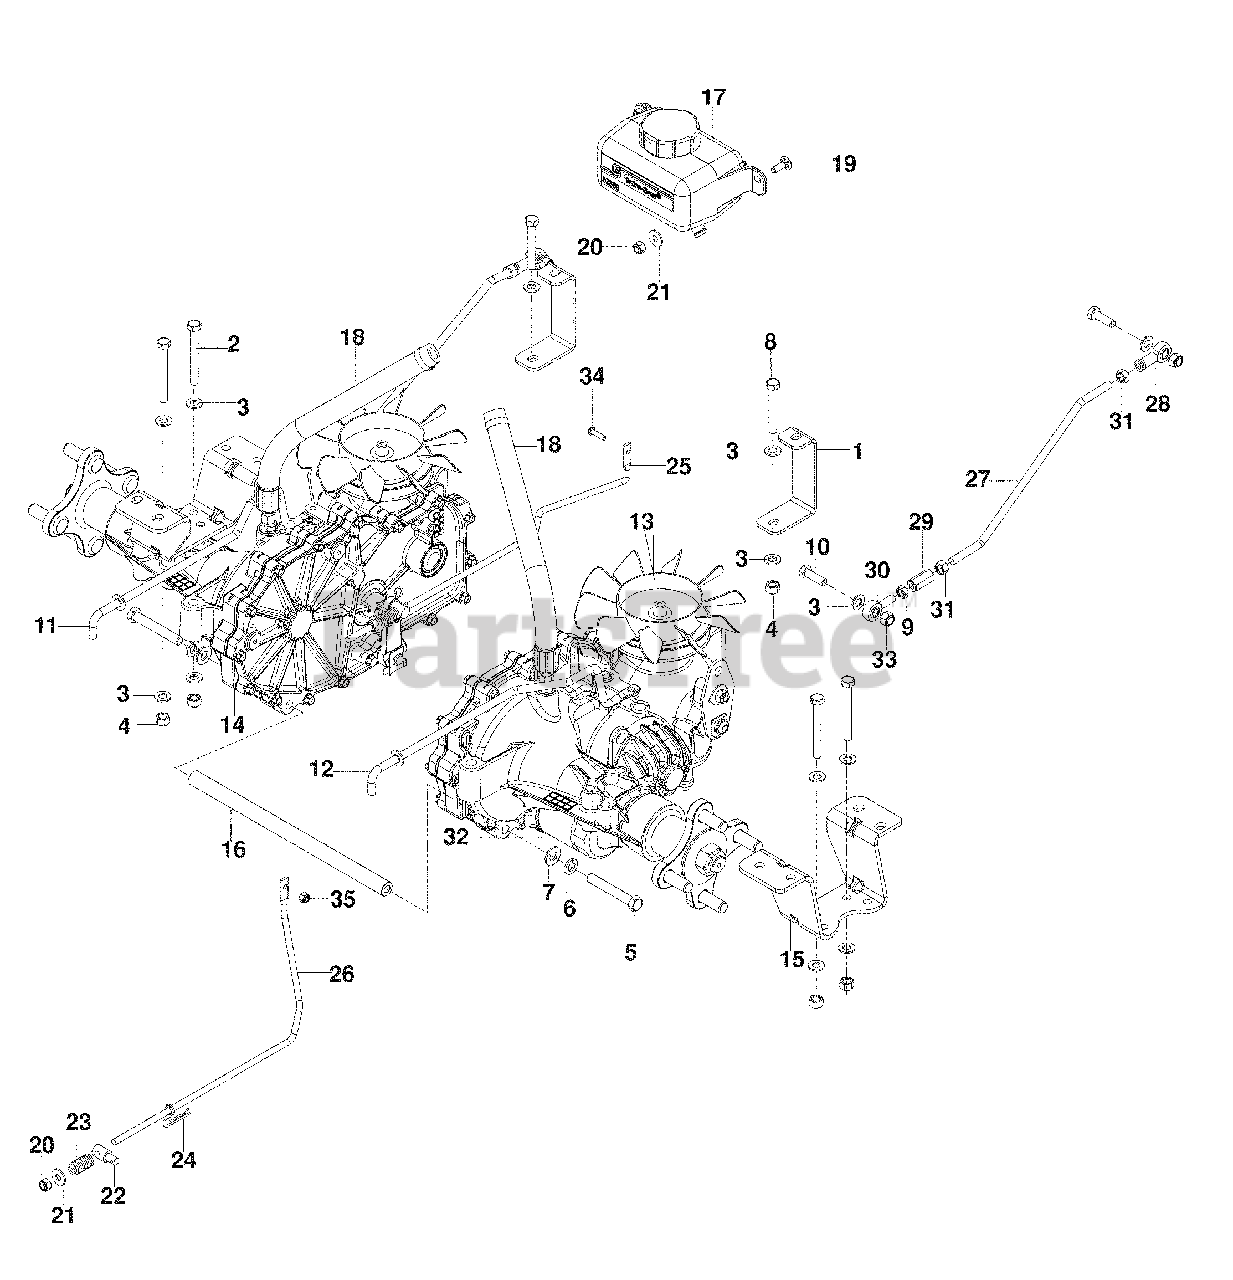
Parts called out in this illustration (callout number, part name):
1	SUPPORT, TRANSMISSION
2	HCS 5/16-18 x 2¾
3	WASHER 5/16 SAE FLAT
4	NUT 5/16-18 HEX NYLOC
5	HCS 3/8-16 x 2½
6	WASHER 3/8 SPLT LOCK
7	WASHER 3/8 SAE FLAT
8	HCS 5/16-18 x 2¼
9	NUT 5/16-24 HEX JAM LH
10	HCS 5/16-18 x 1
11	LINK ARM, BYPASS, RT
12	LINK ARM, BYPASS, LT
13	TRANS, ZT-2800 RT
14	TRANS, ZT-2800 LT
15	EZT MOUNT, REAR
16	SPACER TUBE, EZT
17	EXPANSION TANK w/CAP
19	RHSNB ¼-20 x ¾ GR2
20	NUT ¼-20 HEX NYLOC
21	WASHER ¼ FLAT
22	BRAKE SWIVEL
24	HAIRPIN COTTER
25	LINKAGE, BRAKE LT
26	LINKAGE, BRAKE RT
27	ROD, MOTION CONTROL
28	ROD END RH
29	COUPLER, ROD END
30	ROD END MALE LH
31	NUT 5/16-24 HEX
33	NUT 5/16-18, NYLOC
34	SCREW, #10-24 x ¾
35	NUT 10-24 HEX NYLOC
